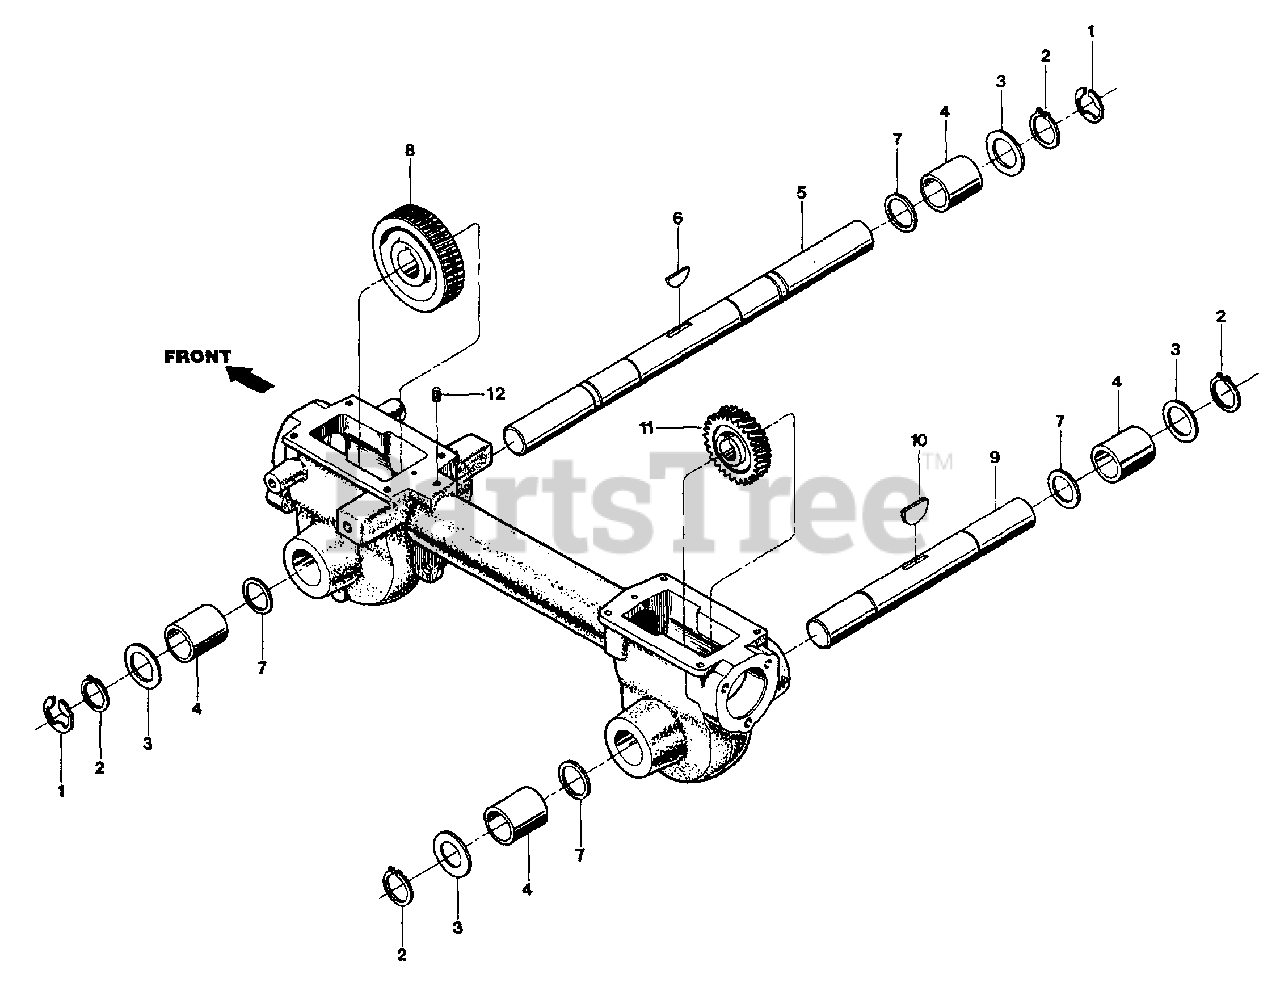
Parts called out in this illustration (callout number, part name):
1	Retainer, Snap Ring, "E" Type
2	Retainer, Snap Ring
3	Shim, 0.062" thick
4	Bronze Bushing
5	Wheel Shaft
6	Key, Hi Pro, 1/4 x 1
7	Spacer
8	Worm Gear, Wheel Shaft
9	Tiller Shaft
10	Woodruff Key
11	Worm Gear, Tiller Shaft
